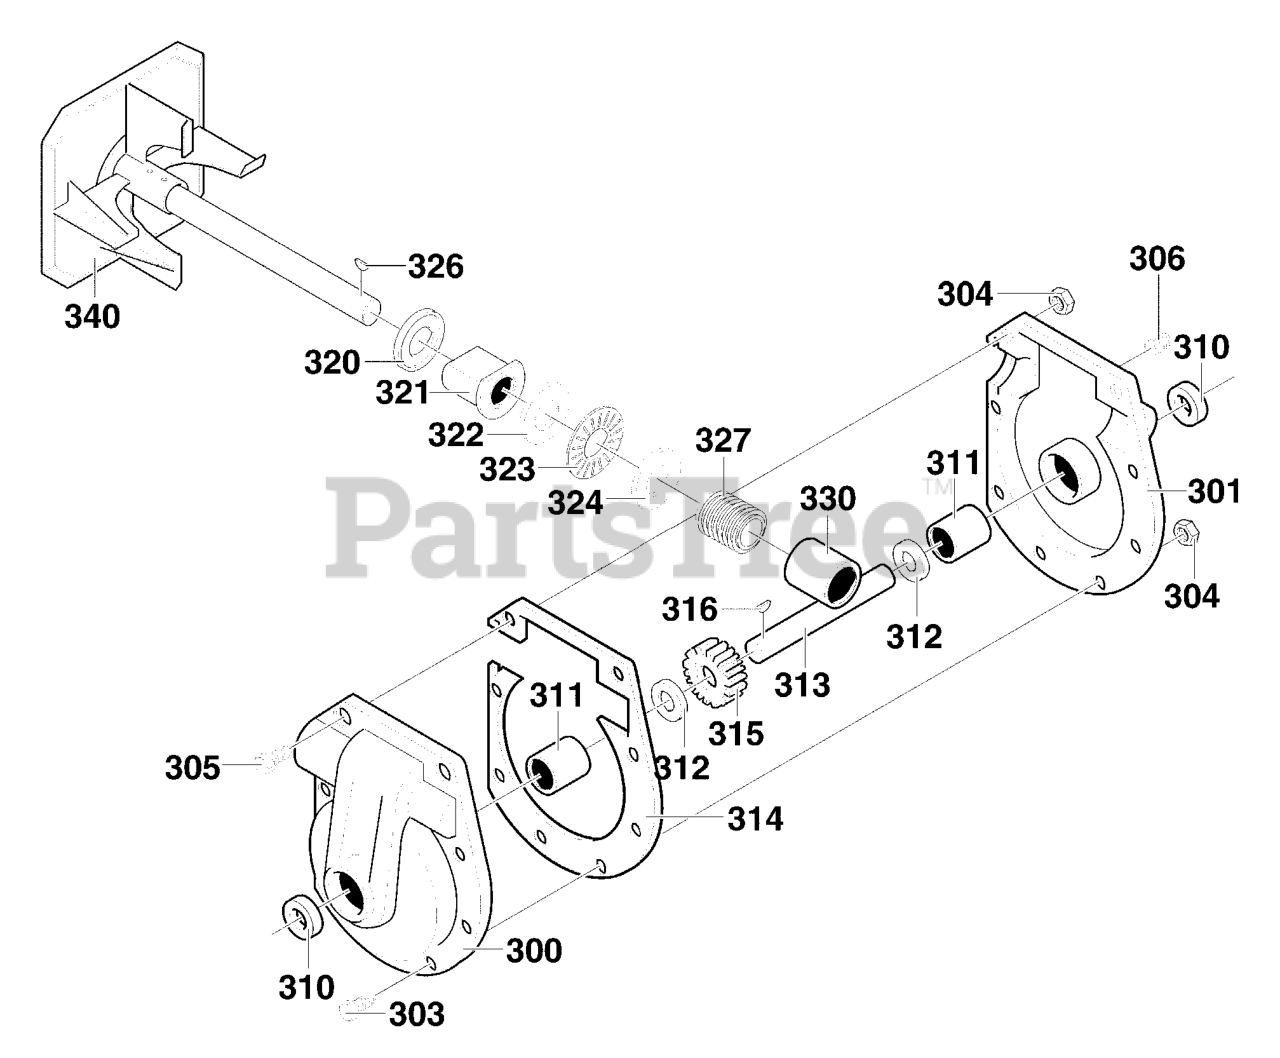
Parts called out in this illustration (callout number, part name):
300	CASE, GEAR RH
301	CASE, GEAR LH
303	SCREW, 5/16-24 x 1.00
304	NUT, 5/16-24 HEX
305	SCREW, 5/16-24 x 1.50
306	PLUG, PIPE
310	SEAL, OIL
311	BEARING, SLEEVE
312	WASHER, FLAT
313	SHAFT, AUGER
314	GASKET, GEAR BOX
315	GEAR, WORM
316	KEY, WOODRUFF #91
320	RING, QUAD
321	BEARING, FLANGE
322	WASHER, FLAT
323	BEARING, ROLL
324	WASHER, FLAT
326	KEY, HI-PRO
327	GEAR, WORM
330	BEARING
